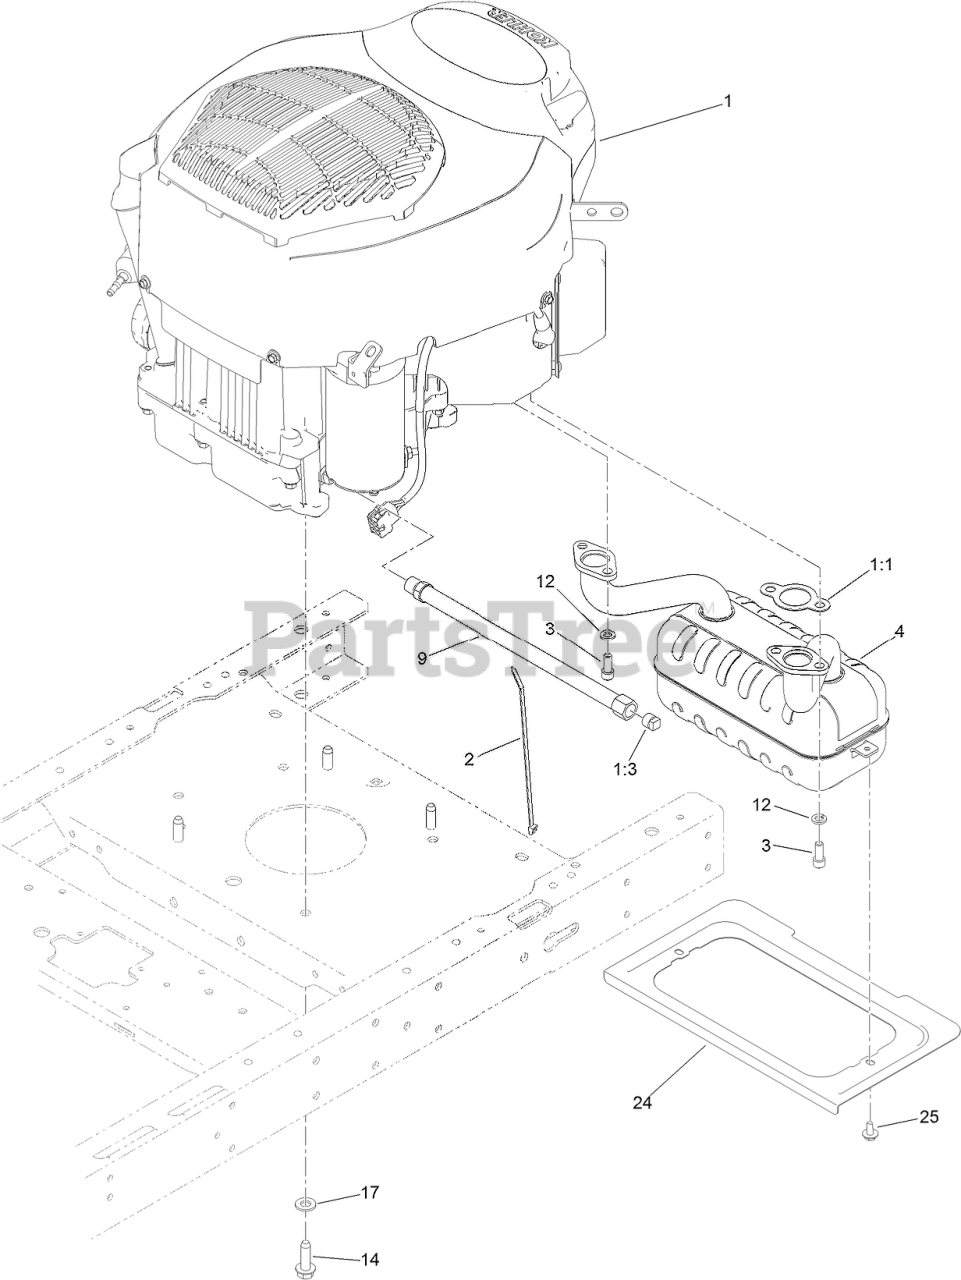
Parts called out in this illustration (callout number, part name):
1	ENGINE-KOHLER 22HP 7000 SERIES AUTOCHOKE
1:1	GASKET-EXHAUST
1:3	PLUG-PIPE, SQH
2	TIE-CABLE
3	SCREW-HSH
4	MUFFLER-KOHLER
9	HOSE-DRAIN, OIL
12	WASHER-LOCK
14	SCREW-TAPTITE
17	WASHER-FLAT
24	SHIELD-HEAT
25	SCREW-HHFTF
